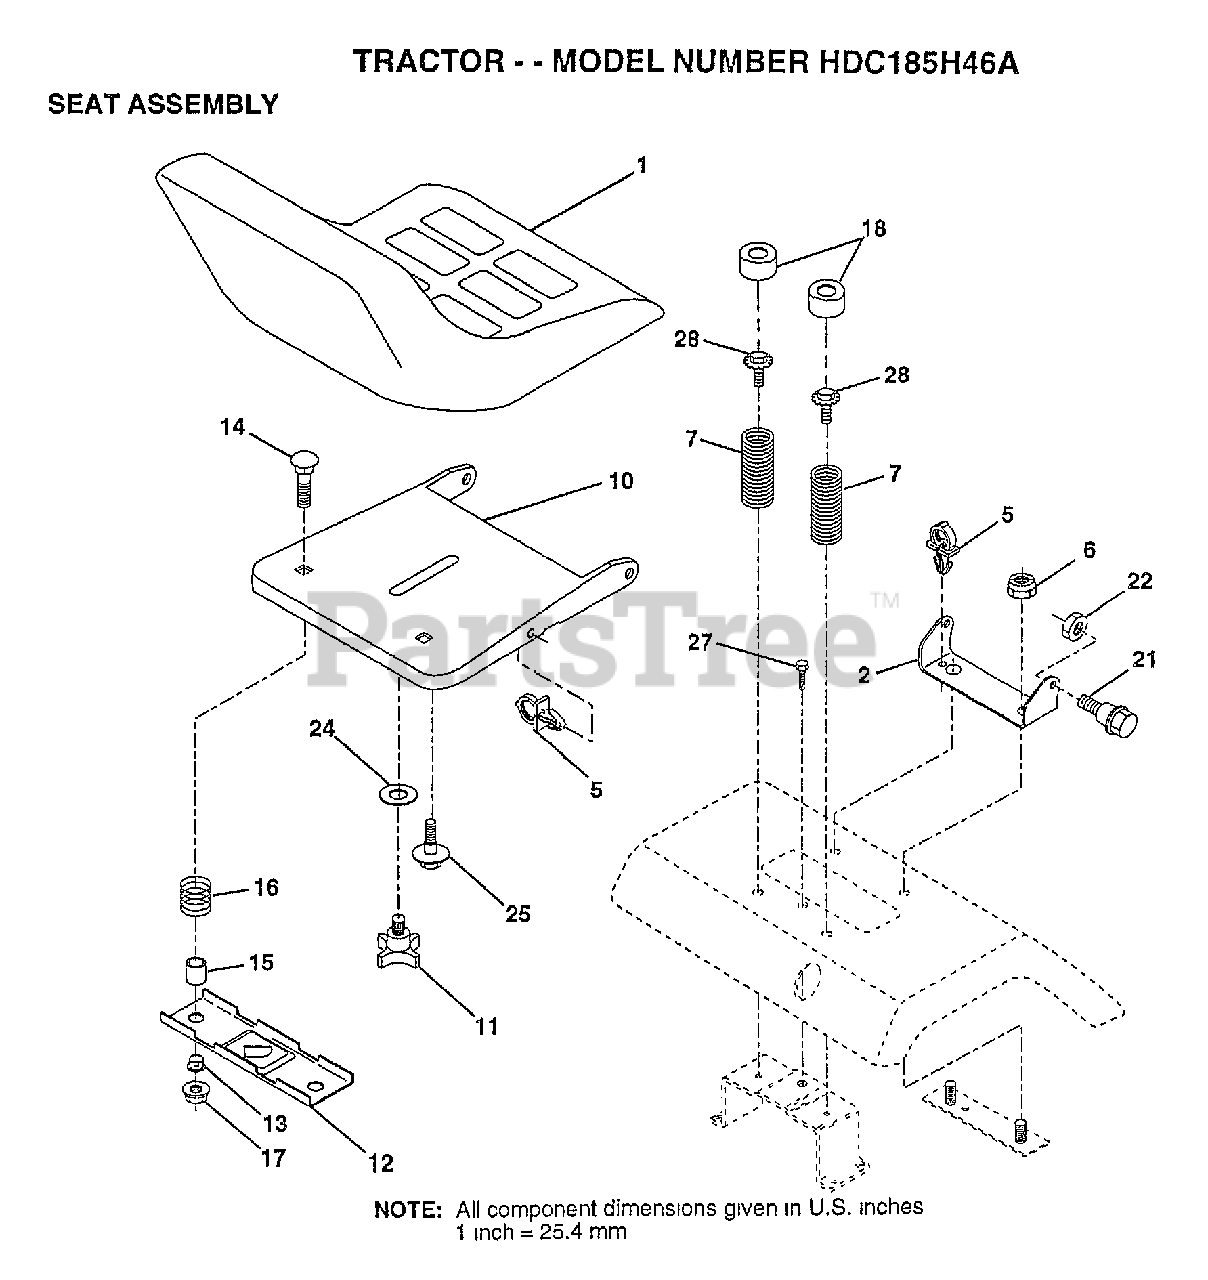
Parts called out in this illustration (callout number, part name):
1	SEAT.2500/1516.BK
2	BRACKET PVT SEAT
5	CLIP.PUSH-IN.HING
6	NUT
7	SPRING COMPRESSIO
10	PAN-SEAT
11	"KNOB 1/2"" YT"
12	BRKT SWITCH
13	BUSHING
15	SPACER SPLIT
16	SPRING COMPRESSED
18	CAP SPRING
21	"BOLT,SHOULDER"
22	NUT
24	WASHER
25	"BOLT,SHOULDER"
27	SCREW LT
28	BOLT.5/16-18.UNC
